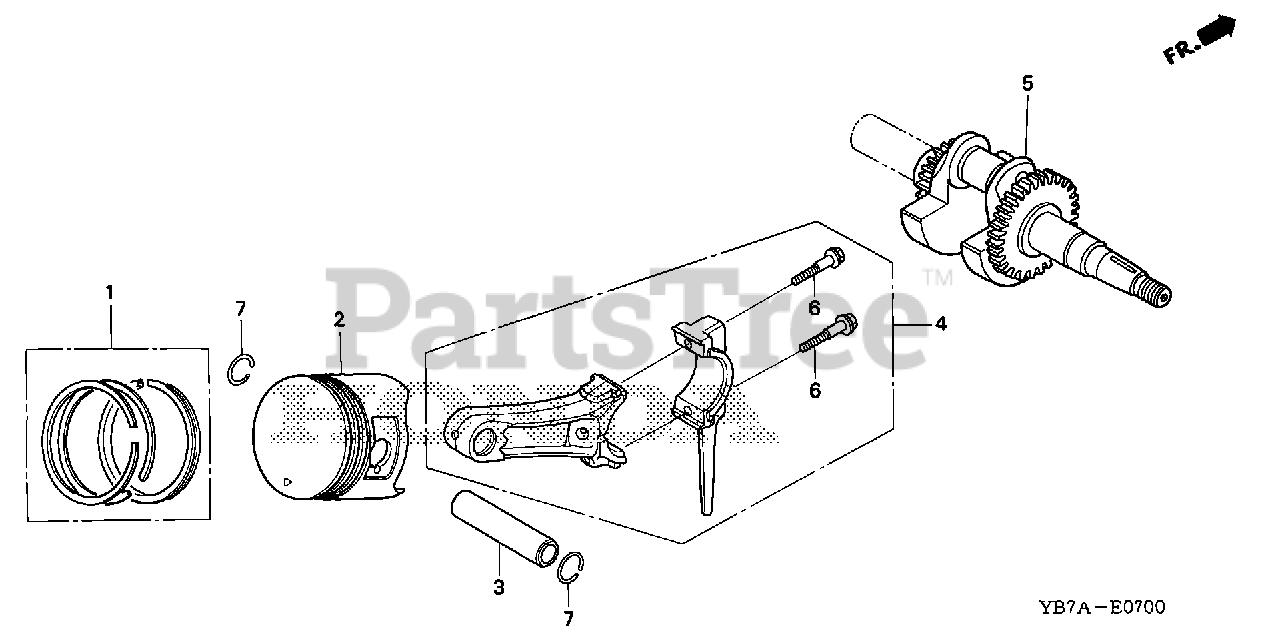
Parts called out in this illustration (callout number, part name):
1	RING SET, PISTON (STD) (TEIKOKU)
1	RING SET, PISTON (STD.) (NIPPON)
1	RING SET, PISTON (STD) (TPR)
1	RING SET, PISTON (0.25) (TEIKOKU)
1	RING SET, PISTON (0.25) (NIPPON)
1	RING SET, PISTON (0.25) (TPR)
1	RING SET, PISTON (0.50) (TEIKOKU)
1	RING SET, PISTON (0.50) (NIPPON)
1	RING SET, PISTON (0.50) (TPR)
1	RING SET, PISTON (0.75) (TEIKOKU)
1	RING SET, PISTON (0.75) (NIPPON)
1	RING SET, PISTON (0.75) (TPR)
2	PISTON (STD)
2	PISTON (0.25)
2	PISTON (0.50)
2	PISTON (0.75)
3	PIN, PISTON
4	ROD ASSY., CONNECTING (0.25 LOWER SIZE) (NOT AVAILABLE)
4	ROD ASSY., CONNECTING (STD)
4	ROD ASSY., CONNECTING (TH)
5	CRANKSHAFT
6	BOLT, CONNECTING ROD
7	CLIP, PISTON PIN (18MM)
